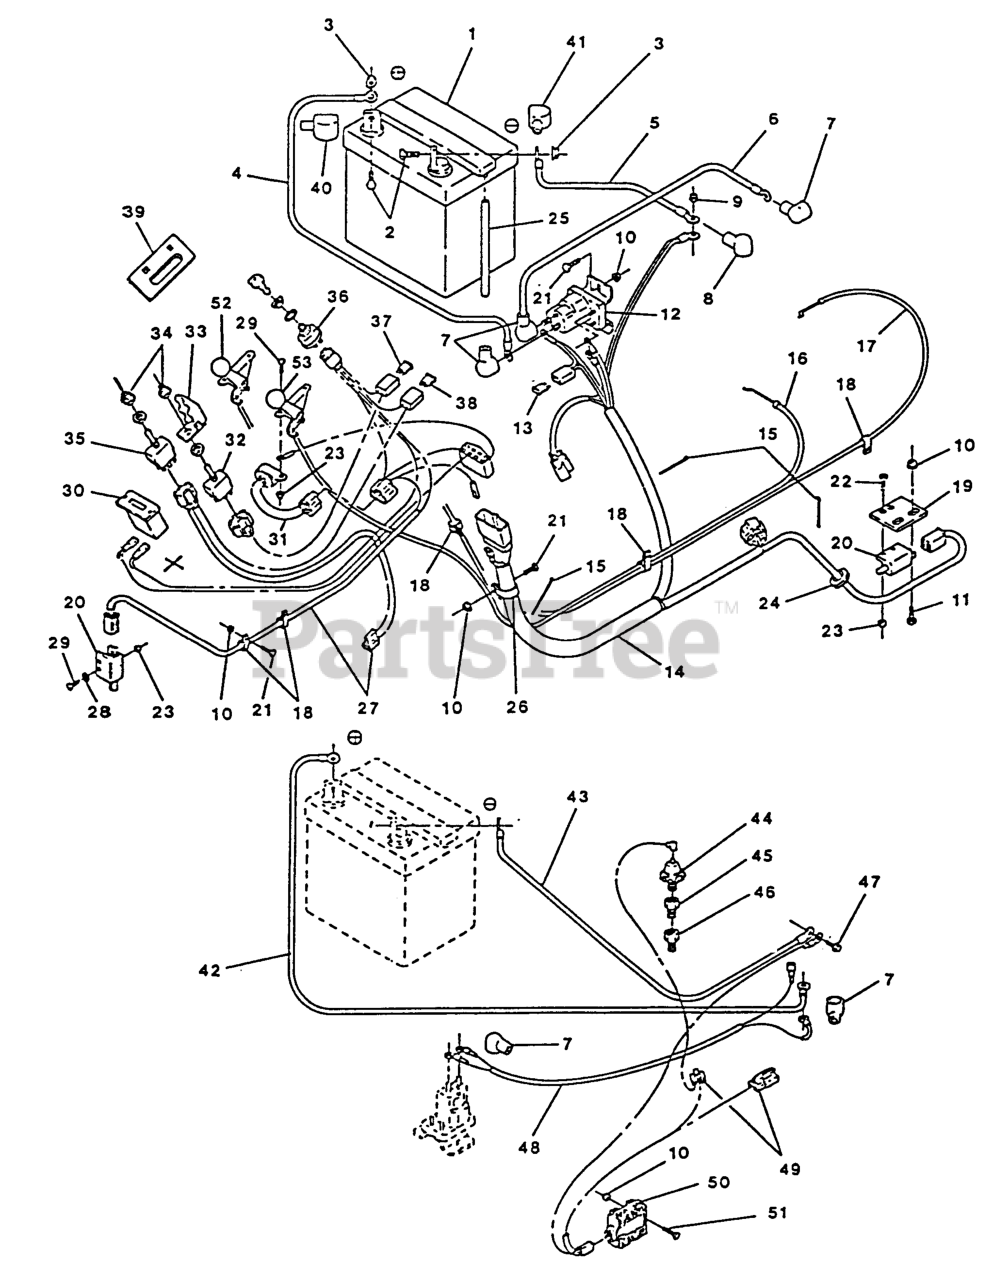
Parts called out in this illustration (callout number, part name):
1	Battery, 12v Manifold
4	WIRE,BATTERY POSITIVE
7	INSULATOR-SOLENOID
13	FUSE-BLADE TYPE, 20 AMP
15	TIE-CABLE
19	BRACKET,SAFETY SWITCH
20	SWITCH-OPEN, NORMALLY
24	GROMMET
26	CLIP-LOOM
30	METER-HOUR
35	SWITCH-TOGGLE, DPDT
38	FUSE-BLADE TYPE, 30 AMP
41	INSULATOR, BATTERY -
43	WIRE-GROUND
44	SWITCH-OIL PRESSURE
47	M8 X 1.25 X 16 Mm Hh Capscrew
50	Voltage Regulator -
52	KNOB-BALL, BLACK
53	KNOB-BALL
